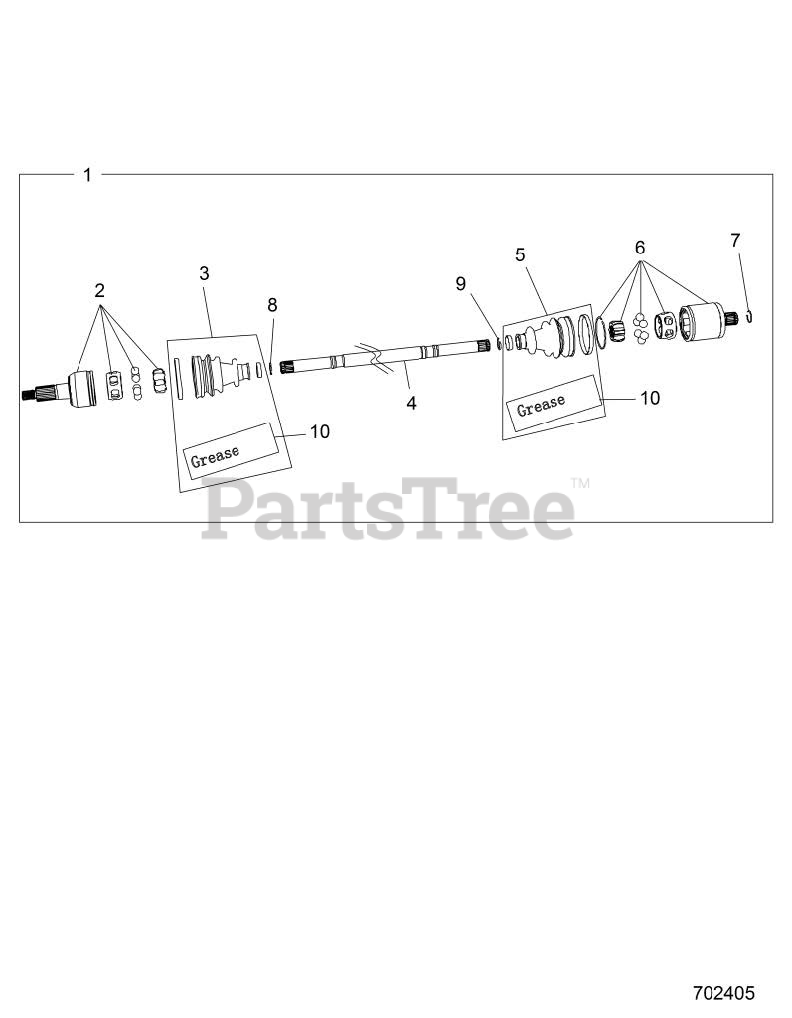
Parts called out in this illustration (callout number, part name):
1	ASM-HALFSHAFT,REAR
2	JOINT, OUTER
3	KIT-BOOT(PR-8071)
5	K - BOOT, INNER
6	JOINT, INNER
9	CIRCLIP(PR-3041)
10	GREASE(K575/VW738)
